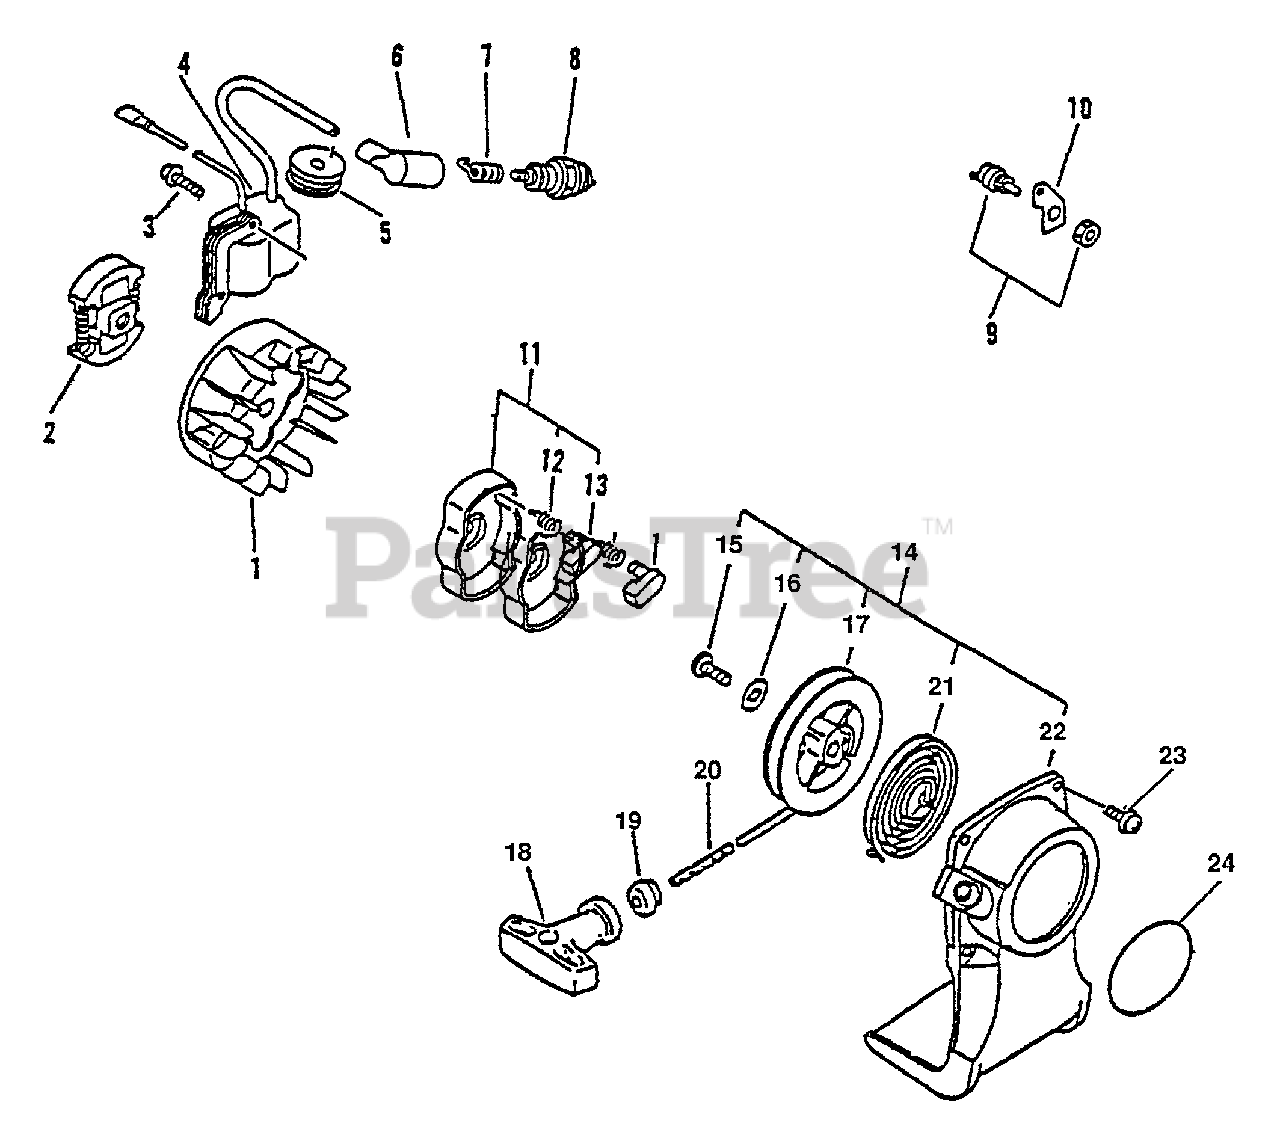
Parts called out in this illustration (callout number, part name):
1	FLYWHEEL
2	CLUTCH ASSY
3	SCREW - 4X22
4	COIL, IGNITION
5	GROMMET
6	CAP, SPARK PLUG
7	TERMINAL, SPARK PLUG CAP
8	SPARK PLUG -- BPM-7A
9	IGNITION SWITCH ASSY
10	BRACKET, SWITCH
11	STARTER PAWL ASSY
12	SPRING, RETURN
13	PAWL, STARTER - BLACK
14	STARTER ASSY
16	WASHER
17	REEL, ROPE
18	GRIP, STARTER
19	GUIDE, ROPE
20	ROPE, STARTER - 3X890
21	SPRING, REWIND
22	CASE, STARTER - BLUE
23	SCREW - 4X16
24	LABEL - ECHO
